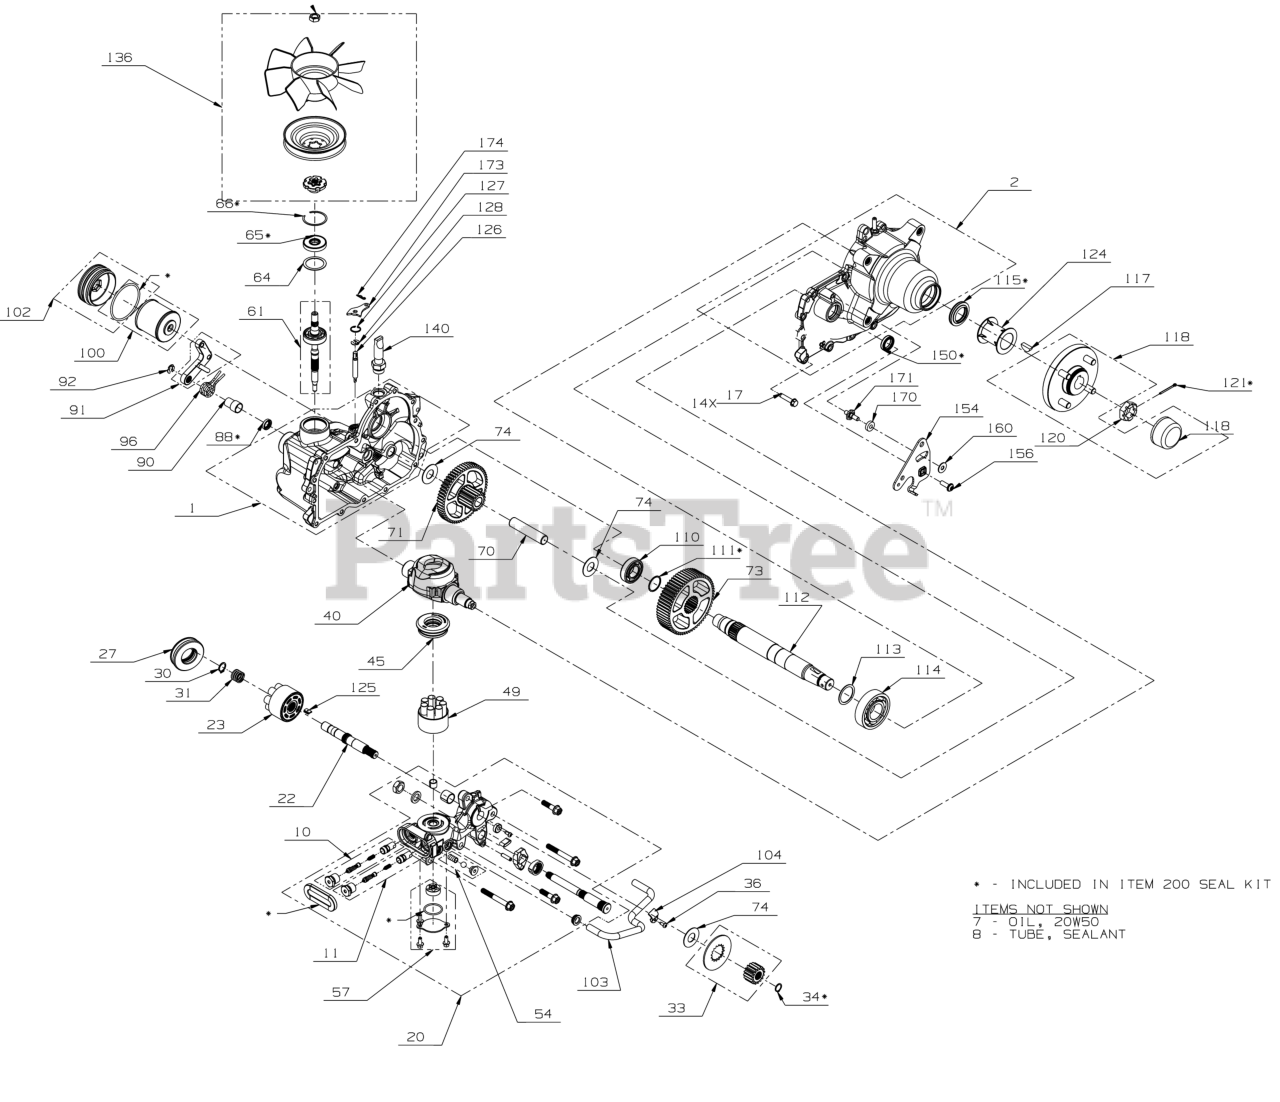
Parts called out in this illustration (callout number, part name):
1	MAIN HOUSING (LH) KIT
2	SIDE HOUSING (LH) KIT
8	SEALANT-HOUSING
10	SHOCK VALVE KIT
11	SHOCK VALVE KIT
17	HOUSING SCREW
20	CENTER SECTION (LH) KIT
22	MOTOR SHAFT
23	16CC CYLINDER BLOCK KIT
27	THRUST BEARING
30	RETAINING RING
31	SPRING-BLOCK
33	BRAKE ROTOR GEAR KIT
34	RETAINING RING
36	SCREW-SELF TAPPING
40	16CC MACHINED SWASHPLATE
45	THRUST BEARING
49	BLOCK KIT-CYLINDER
54	CHARGE RELIEF KIT
57	CHARGE PUMP KIT
61	INPUT SHAFT KIT
65	LIP SEAL
66	INTERNAL RETAINING RING 1.875
70	JACK SHAFT .78 X 3.63
71	GEARS KIT
74	FLAT WASHER .80 X 1.70 X .05
88	BRAKE SEAL
90	SPRING SPACER
91	LH BRAKE KIT
92	RETAINING RING
96	TORSION SPRING
100	FILTER KIT
102	FILTER CAP KIT
103	FILTER TUBE-LH
104	TUBE CLAMP
110	BALL BEARING
111	RETAINING RING 1.25
112	AXLE SHAFT
113	FLAT WASHER 1.40 X 1.75 X .05
114	BALL BEARING 35 X 80 X 21
115	LIP SEAL 1.375 X 2.062 X .250
117	WOODRUFF KEY 5/16 X 1
118	4 BOLT HUB KIT
120	SLOTTED 1-20 NUT
121	COTTER PIN 9/64 X 1.5
124	AXLE TUBE 1.40 X 2.22
125	BYPASS PLATE
126	BYPASS ROD
127	RETAINING RING
128	RETAINING RING
136	FAN/PULLEY KIT
140	STRAIGHT FITTING 7/8 SAE
150	LIP SEAL 22 X 32 X 7 TC
154	ARM-CONTROL (LH)
156	SCREW 5/16
160	FLAT WASHER
170	PLASTIC WASHER .32 X .80 X .21
171	STUD-SHORT
173	BYPASS ARM
174	HAIRPIN COTTER PIN
